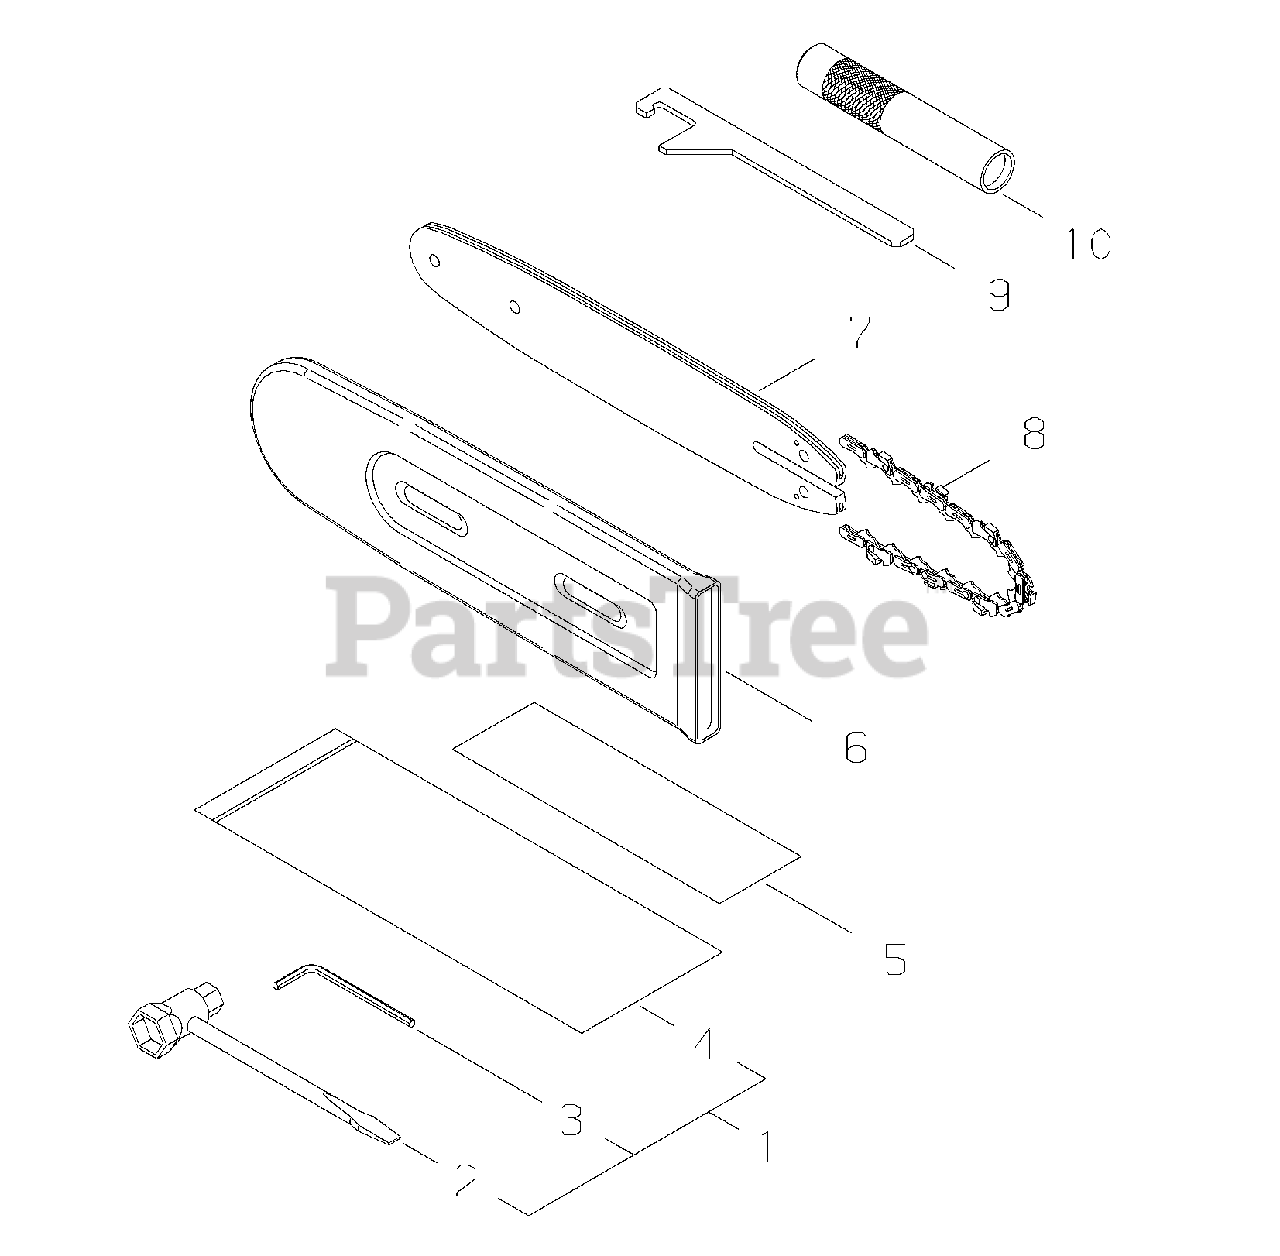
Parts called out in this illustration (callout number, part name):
1	TOOL KIT
2	T-WRENCH
3	HEX KEY - 4mm
4	BAG, TOOL
5	LABEL - CAUTION
6	COVER, GUIDE BAR
7	GUIDE BAR - 8" (20cm)
7	GUIDE BAR - 10" (25cm)
8	SAW CHAIN - 8" (20cm)
8	SAW CHAIN - 10" (25cm)
8	SAW CHAIN - 12" (30cm)
9	HOOK SPANNER
